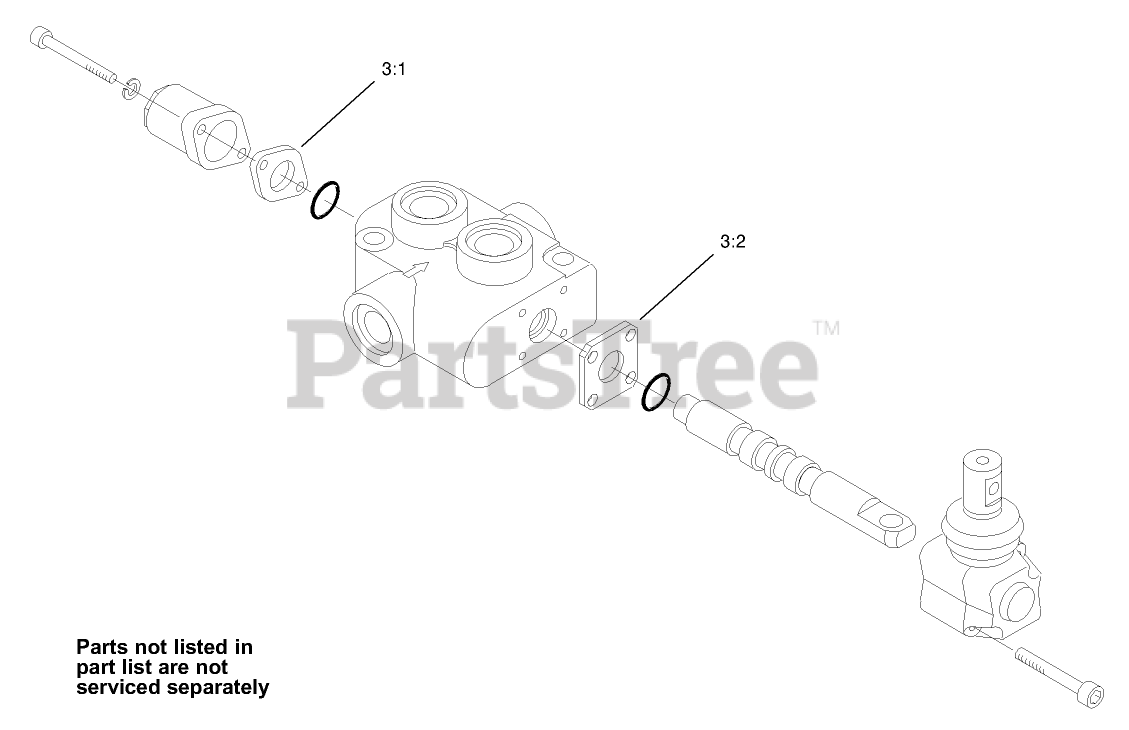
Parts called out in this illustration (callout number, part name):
3	SEAL KIT
3:1	GASKET
3:2	GASKET
